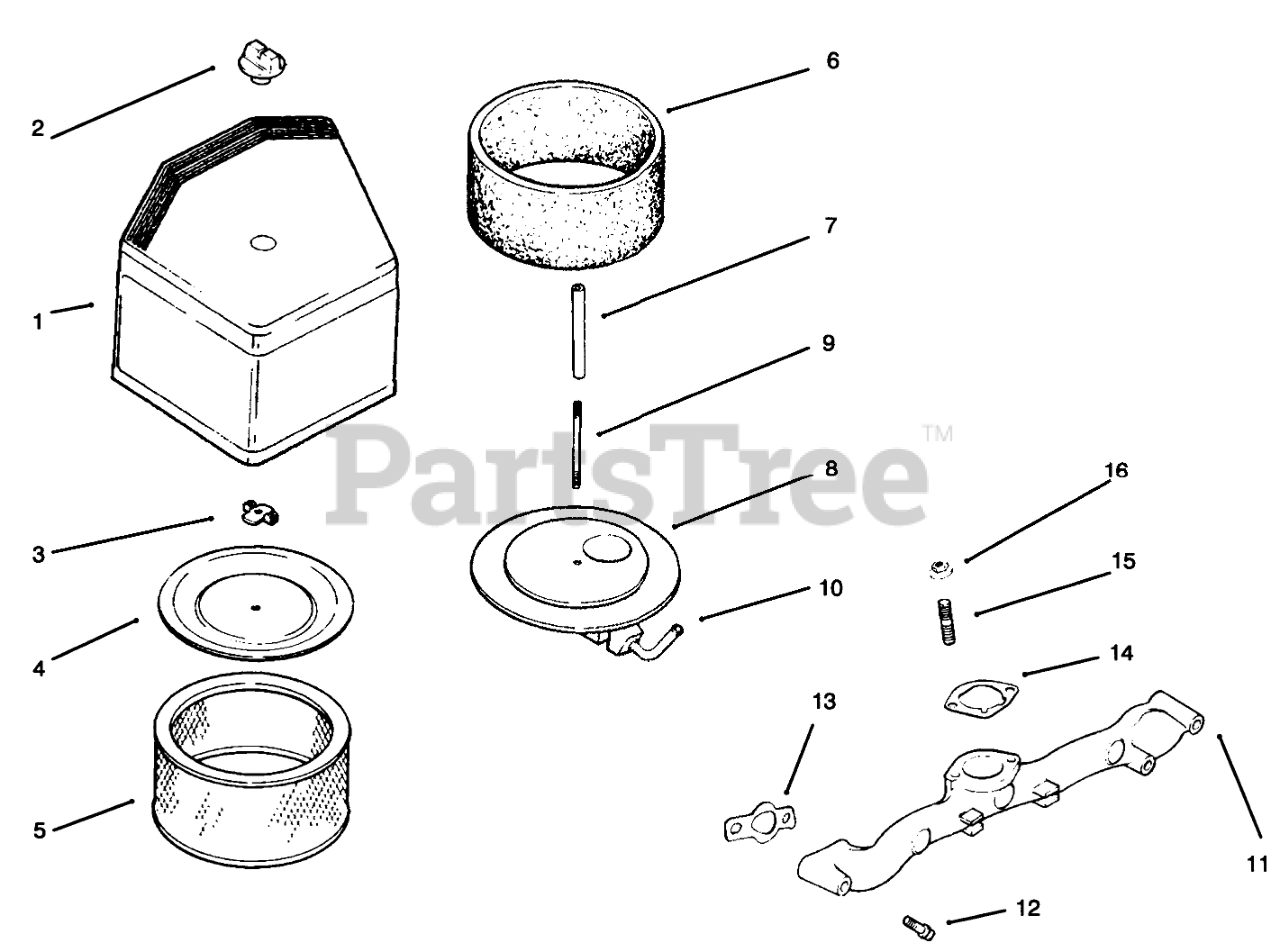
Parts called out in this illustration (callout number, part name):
1	Kit-Air Cleaner Cover (Incl. Ref.# 2)
2	Knob-Cover
3	Nut-Wing
4	Cover-Element
5	Precleaner
6	Element
7	Seal
8	Elbow-Air Cleaner (Incl. Ref. # 9-10)
9	Stud
10	Fitting
11	Manifold-Intake
12	Screw
13	Gasket-intake Manifold
14	Gasket-A/C Base
15	Stud
